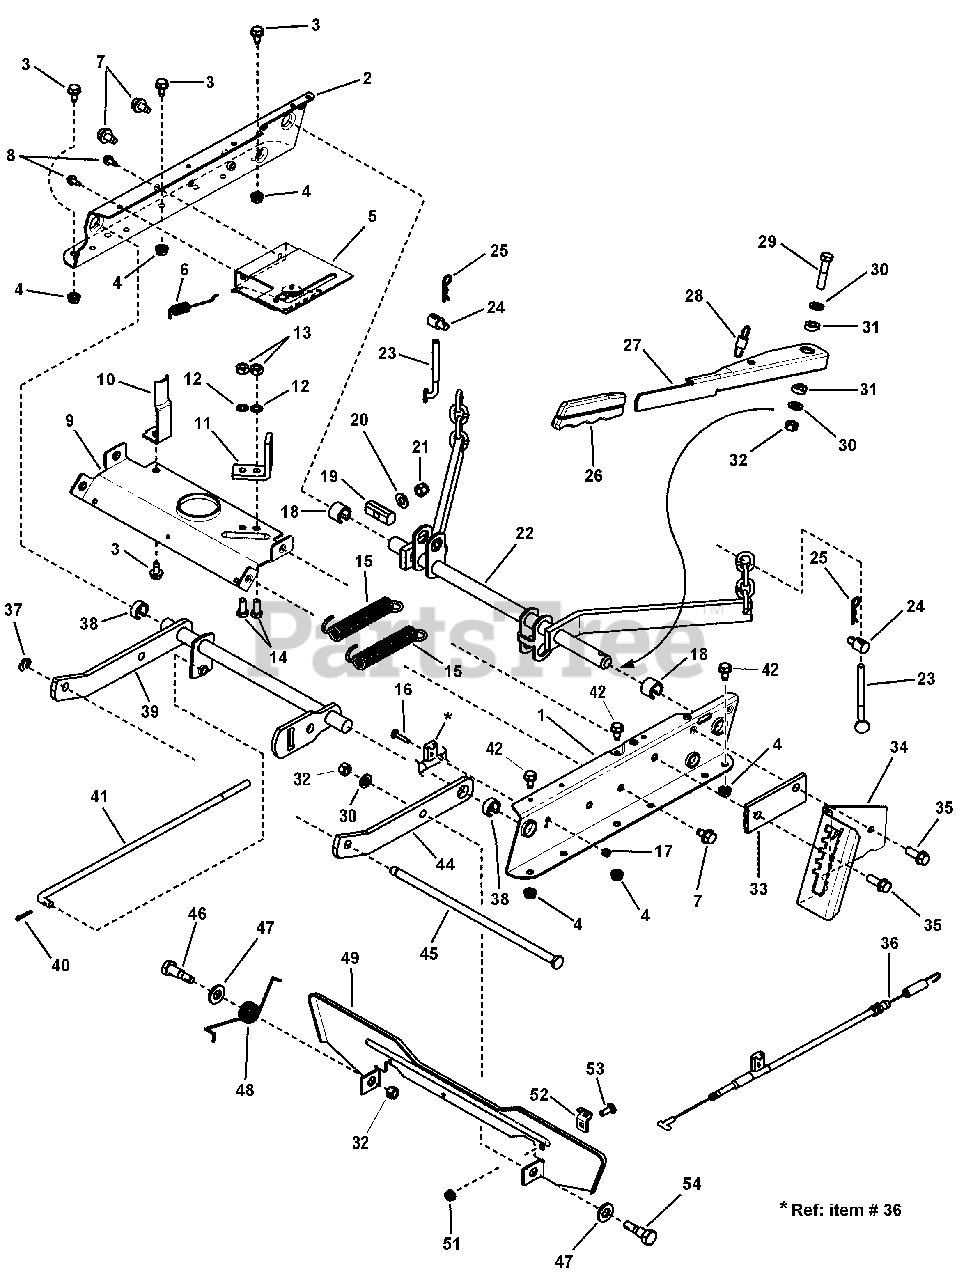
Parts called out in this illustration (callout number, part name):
1	RAIL, Deck Lift, Left Hand
2	RAIL, Deck Lift, Right Hand
3	BOLT, 1/4-20 x 1/2 Hex Flange Lock, GR 5, ZP
4	NUT, Serrated Lock Flange, 5/16-18
5	CLUTCH PLATE ASSY, RLM
6	SPRING, Latch, .072 DIA., 3.6" Long
7	SCREW, 3/8-16 x 5/8" Hex Washer Self-Tap, BP
8	SCREW, 5/16-18 X .625, Hex Washer Head, Thread Roll, Zinc/Clear
9	BRACE, Top Rail
10	GUIDE, Belt
12	WASHER, 5/16, Internal Lock, Zinc/Clear
13	NUT, 5/16-24, Hex, GR5, Zinc/Clear
14	SCREW, 5/16-24 x 3/4 Hex Head Cap, GR 5
15	SPRING, Assist
16	BOLT, #10-24 x 1" Flat Head Square Neck
17	NUT, Nylock, #10-24
18	RING, Rear Lift Arm (Blue)
19	PIVOT, Leveling
20	WASHER, .406
21	NUT, 3/8-24, Hex Nylock, Zinc/Clear
22	WELDMENT, Rear Lift Arm
23	ADJUSTER, Chain (5/16-18 X 3.68")
24	SWIVEL, ADJUSTABLE, 5/16-18+.109 hole
25	PIN, Hair, 3/32 x 1 5/8
26	GRIP, DECK LIFT
27	LEVER, Height of Cut
28	SPRING, Lever
29	SCREW, 3/8-24 x 1-3/4" Hex Head Cap, GR 5
30	WASHER, 13/32" ID x 1.25" x 1/8" Thick, Flat, ZP
31	SPACER, Deck Lift
32	NUT, 3/8-24 Hex Center Lock, GR B, YZ
33	SPACER, Detent
34	DETENT, Height Adjust
35	SCREW, 3/8-16 X 1.0, Hex Washer Self-Tap, ZC/CL
36	CABLE ASSEMBLY, No Reverse in Mow
37	RING, .438 External Retaining
38	RING, Front Lift Arm (Red)
39	WELDMENT, Front Lift Arm
40	PIN, 1/8 X 0.75, Cotter, Zinc/Clear
41	ROD, Leveling (3/4-24 thread)
42	BOLT, 5/16-18 x 5/8 Hex Flange lock, GR 5, YZ
44	ARM, Front Lift
45	ROD, Deck Support (Front Lift Arm to Front End)
46	BOLT, 3/8-24 X 9/16, 1/2 Dia. Shoulder, ZP
47	WASHER, .531 ID X 1.063 OD X .094 Thk, Flat, ZC/CL
48	SPRING, Pedal
49	FOOT PEDAL, Blade Stop Control
51	NUT, 1/4-20 Hex Flange Lock, GR 5, Zinc/Clear
52	CLIP, Cable
53	BOLT, 1/4-20 x 3 x 3/4" Square Neck Carriage, GR 5
54	SHOULDER BOLT, 3/8-24 w/Nylon Patch, GR 5
